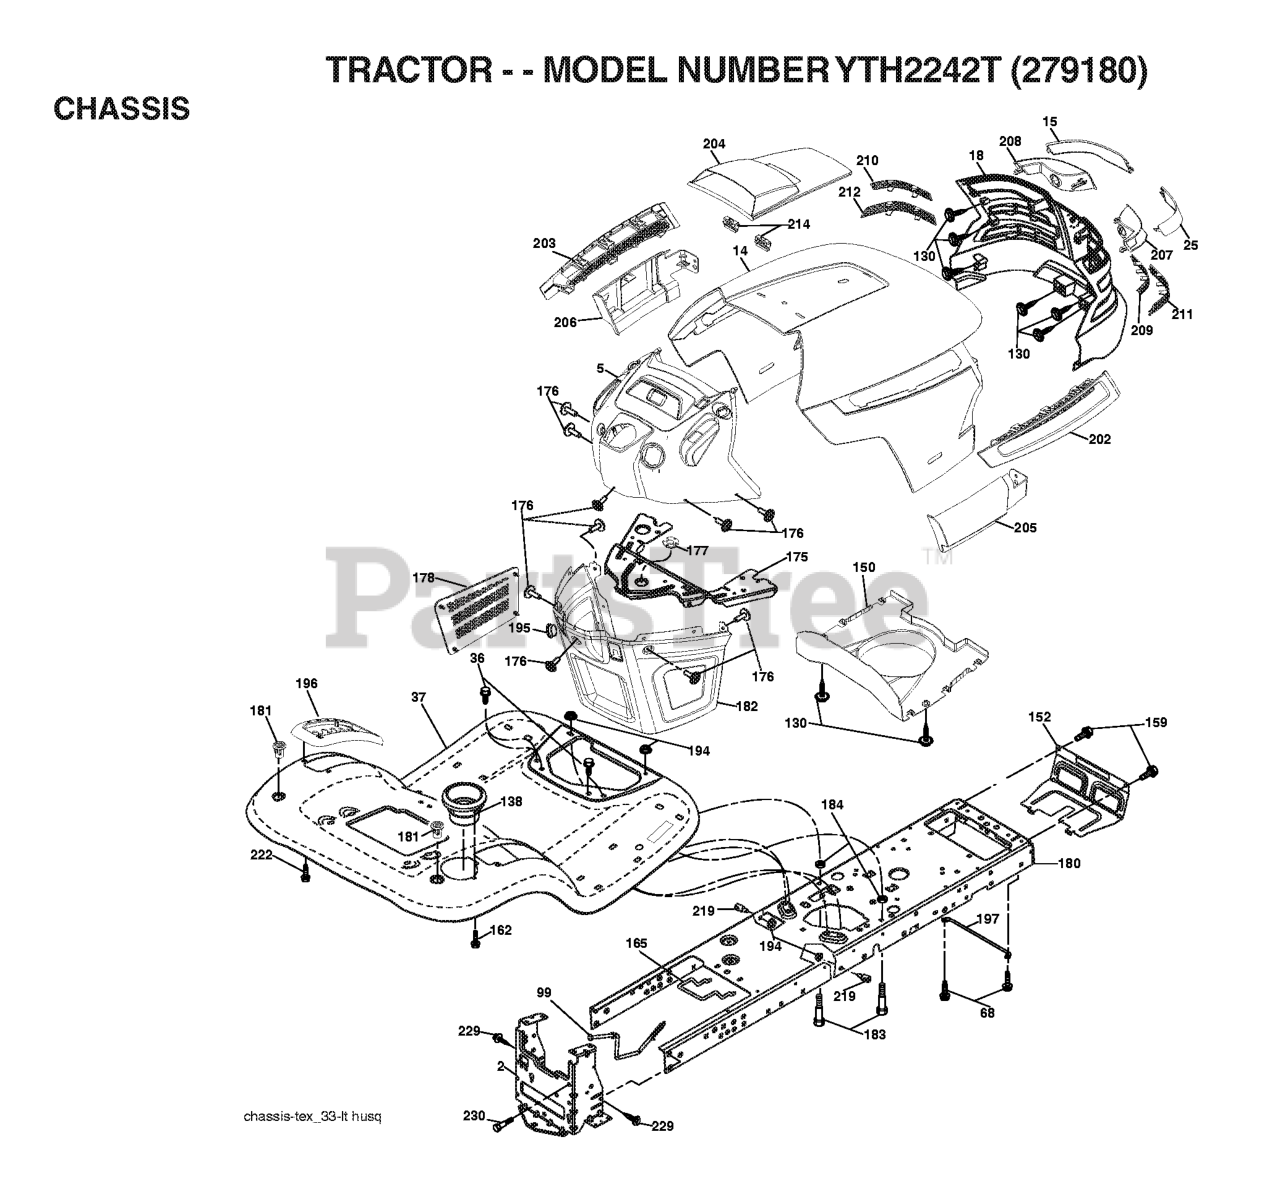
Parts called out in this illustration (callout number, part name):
2	DRAWBAR.1PC.NSTL
5	DASH.HUSQ.UPR.ELE.SVMD
14	HOOD.PNT.HUSQVARNA.GT.
15	LENS.LH.TEX.GT.HUSQ.CL
17	SCREW 3/8-16X3/4
18	GRILLE.ASM.TEX.GT.HUSQ
25	LENS.RH.TEX.GT.HUSQ.CL
36	SCREW 5/16"
68	Screw 5/16-18 x 1/2 Hex, Self Tapping 5/16-18 x 1/2
130	SCREW
138	CUPHOLDER.TL.TEX.418
150	AIR.DUCT.TEXGT.HUSQ.SV
152	SHIELD.BROWNING/DEBRIS
161	CONSOLE.FUEL.WINDOW.HU
162	SCREW.HI-LO.CONSOLE
175	PLATE.CROSSMEMBER.HUSQ
176	SCREW.#10-24X5/8.RN.QU
177	BUSHING, STEERING
178	CARGO.ASM.NET.TXGT.W/C
180	CHASSIS.STAMPING.LT/GT
181	BUSHING.MNT.FEND.CRGO.
182	DASH.LOWER.COMMON.12V.
183	BOLT.5/16-18X1-1/4 FULL.THREAD
184	SPACER.FENDER
194	NUT LOCK HEX FLANGE 5/16-18
195	PLUG.HOLE.DASH.LOWER.12V.BLK
196	CONSOLE.ASM.DECK.LIFT.
202	VENT.SIDE.HOOD.HUSQ.RH.GREY
203	VENT.SIDE.HOOD.HUSQ.LH.GRAY
204	VENT.TOP.HOOD.HUSQVARN
205	SKIRT.HOOD.SIDE.HUSQ.RH.GREY
206	SKIRT.HOOD.SIDE.HUSQ.LH.GREY
207	BEZEL.RH.TEX.GT.HUSQ
208	BEZEL.LH.TEX.GT.HUSQ
209	INSERT.HEX.GRILL.HUSQ.GREY
210	INSERT.HEX.GRILL.HUSQ.
211	INSERT.HEX.GRILL.HUSQ.
212	INSERT.HEX.GRILL.HUSQ.
214	CLIP.RETAINER.TINNER.
217	ROD PIVOT CHASSIS/HOOD
219	STUD.FASTNER.W/ANTI-ROTATE
221	REFLECTOR.LH.TEX GT HU
222	SCREW.1/4-20X5/8
229	SCREW 3/8-16X1
230	SHOULDER BOLT 5/16-18TT
